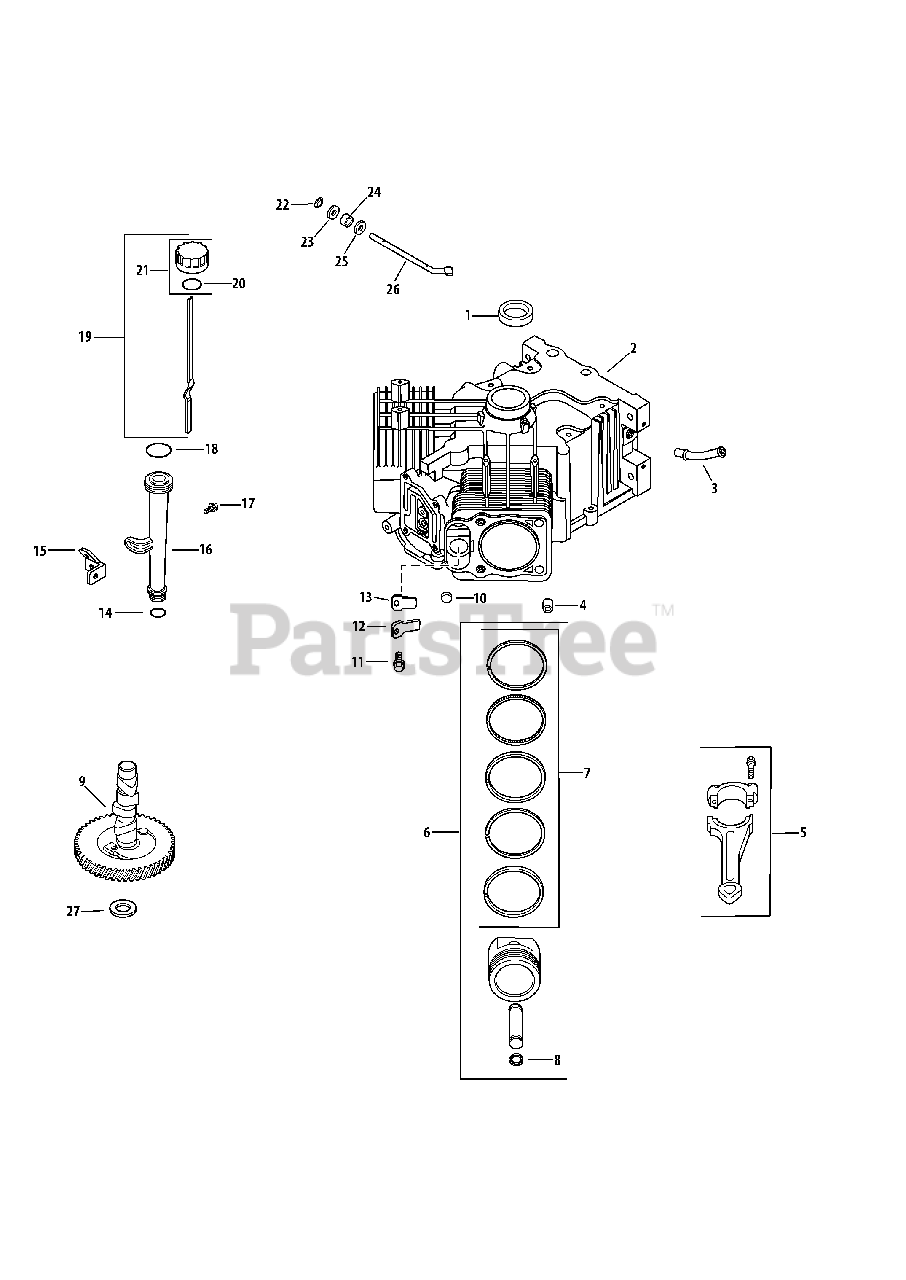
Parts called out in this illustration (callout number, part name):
2	Crankcase
5	Connecting Rod Assembly
5	Connecting Rod Assembly (.25)
6	Piston Kit w/ Ring Set (Standard)
6	Piston Kit w/ Ring Set (.08)
6	Piston Kit w/ Ring Set (.25)
6	Piston Kit w/Ring Set (.5)
7	Piston Ring Set (Standard)
8	Piston Pin Retainer
9	Camshaft Kit
11	Flange Screw, M5 x .8 X 10
12	Breather Reed Retainer
13	Breather Reed
14	Lower Oil Fill Tube O-Ring
15	Oil Fill Tube Bracket
16	Tube Assembly
17	Flange Screw, M5 x 0.8 x 16
18	Upper Oil Fill Tube O-Ring
19	Dipstick Assembly
20	Dipstick O-Ring
21	Oil Fill Cap Kit (Yellow)
22	Retainer Ring
23	Flat Washer, 9 mm
24	Governor Cross Shaft Seal
25	Flat Washer, 11/32
26	Governor Cross Shaft
27	Camshaft Shim (White .028)
